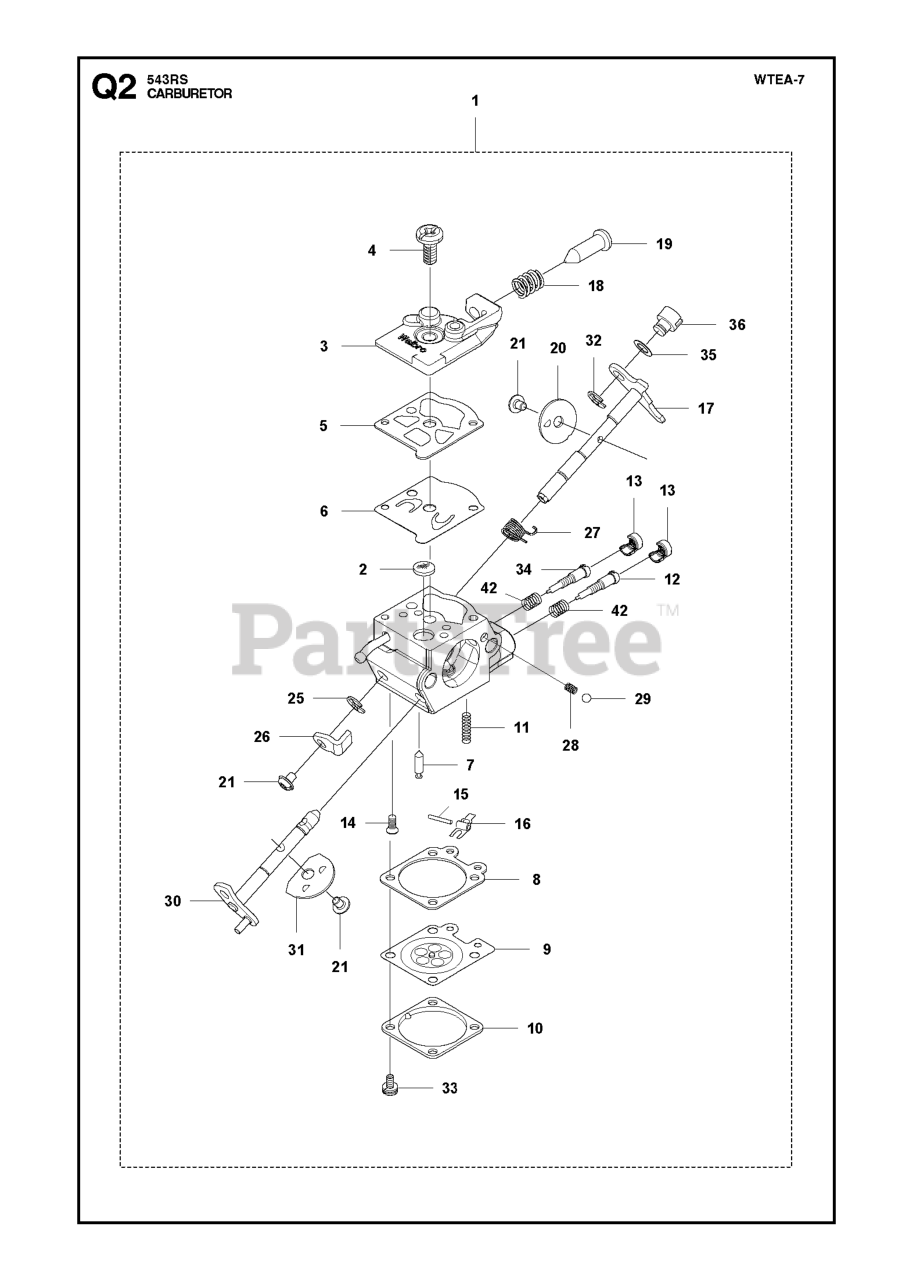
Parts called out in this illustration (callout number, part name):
1	Carburetors
2	SCREEN
7	VALVE INLET
13	CAP LIMITER
17	SHAFT ASSY THROTTLE
19	SCREW, IDLE
20	VALVE, THROTTLE
26	LEVER THROTTLE
28	CHOKE SPRING
31	VALVE CHOKE
33	SCREW ASSY
42	SPRING
